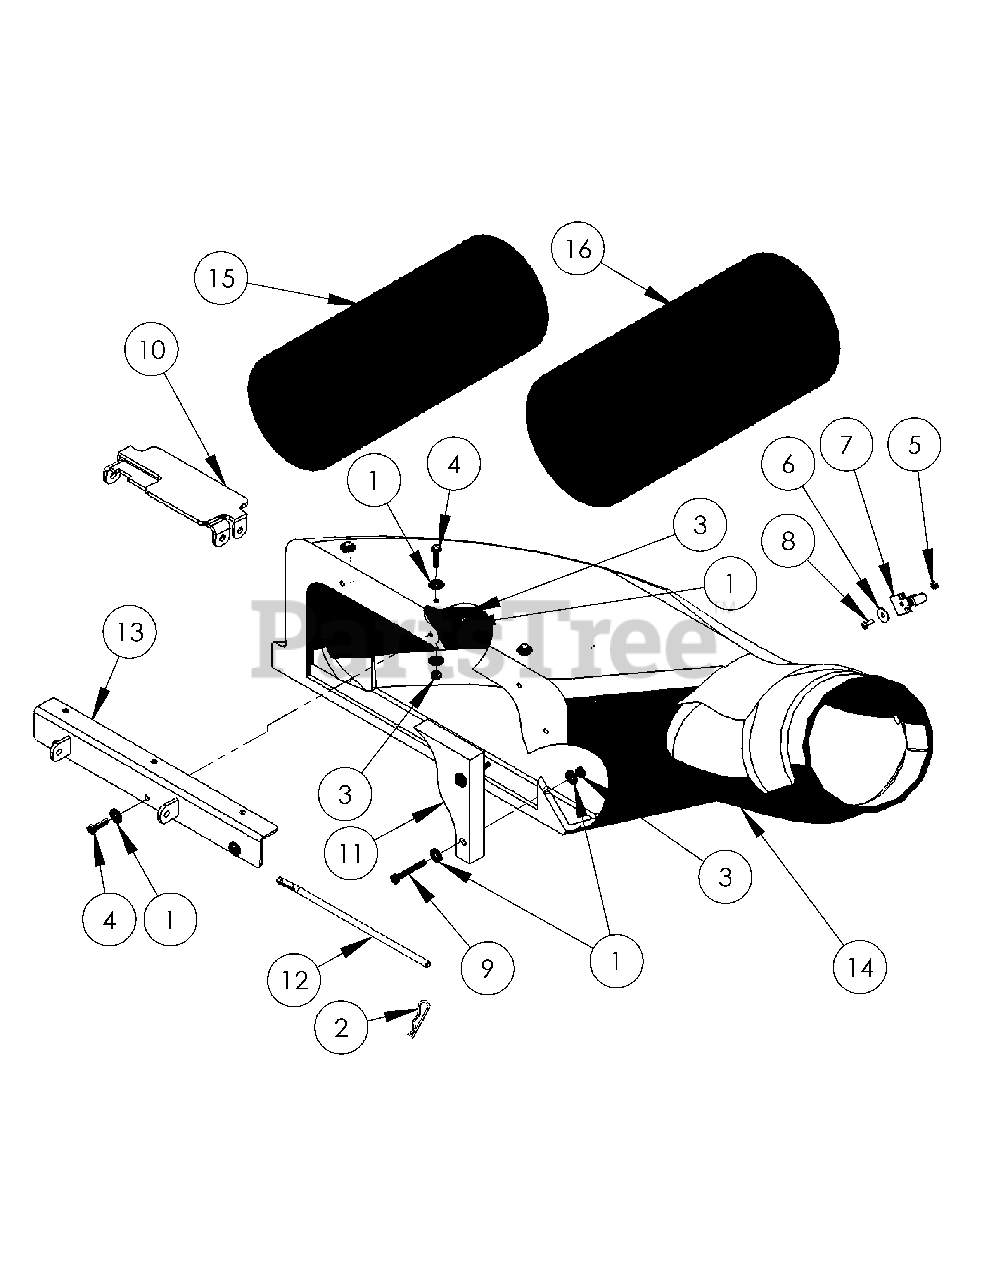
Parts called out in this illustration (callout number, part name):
1	1/4" USS Washer
2	Hair Pin, 0.091 X 1.875
3	1/4-20 Nylon Insert Nut
4	Cap Screw 1/4-20 X 1.00
5	#10-24 Nylon Insert Nut
6	#10 Fender Washer
7	Spring Clip
8	#10-24 X 3/4" Screw
9	CS 1/4-20 X 2 G5
10	Quick Change Brkt Assy
11	60" Boot Filler
12	Mounting Pin, 'L'
13	Transition Boot Bracket
14	Transition Chute 6"-7" .25" Wall
15	6" Hose CCY CTC2
16	7" Hose CCY CTC2
